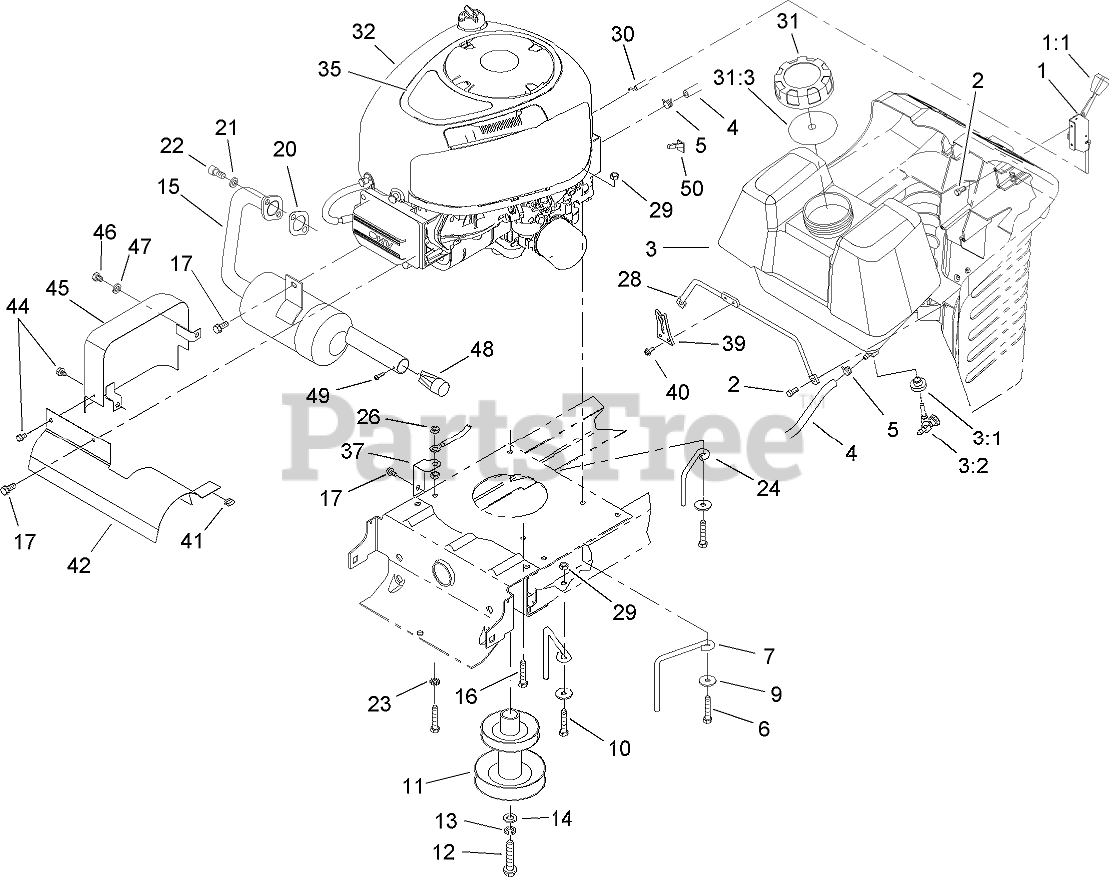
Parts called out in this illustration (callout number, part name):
1	THROTTLE CONTROL ASM
2	SCREW-SPECIAL
3	GAS TANK ASM
3:1	BUSHING
3:2	VALVE-FUEL
4	HOSE-FUEL
5	CLAMP-HOSE
6	SCREW-HH
7	GUIDE-BELT, ENGINE
9	WASHER-PIVOT
10	SCREW-HH
11	Pulley-Engine
12	SCREW-HH
13	WASHER-LOCK
14	WASHER-FLAT
15	MUFFLER
16	SCREW-HWH, TAPTITE
17	SCREW-HWH
20	GASKET-EXHAUST
21	WASHER-LOCK
22	SCREW-HSH
23	WASHER-LOCK
24	GUIDE-BELT, RH
26	NUT-KEPS
28	ROD-TANK, GAS
29	NUT-LOCK, NI
30	THROTTLE CABLE ASM
31	GAS CAP ASM
31:3	GASKET-CAP, GAS
32	ENGINE-17HP, BRIGGS AND STRATTON
35	DECAL-ENGINE
37	BRACKET-GROUND
39	LATCH-HOOD
40	SCREW-HWH
41	CLIP-TINNERMAN
42	SHIELD-MUFFLER
44	SCREW-HWHTF
45	HEAT SHIELD ASM
46	SCREW-HH
47	WASHER-LOCK
48	SCREEN-SILENCER, EXHAUST
49	SCREW-THD FORM, HWH
50	REDUCER-THROTTLE, RPM
